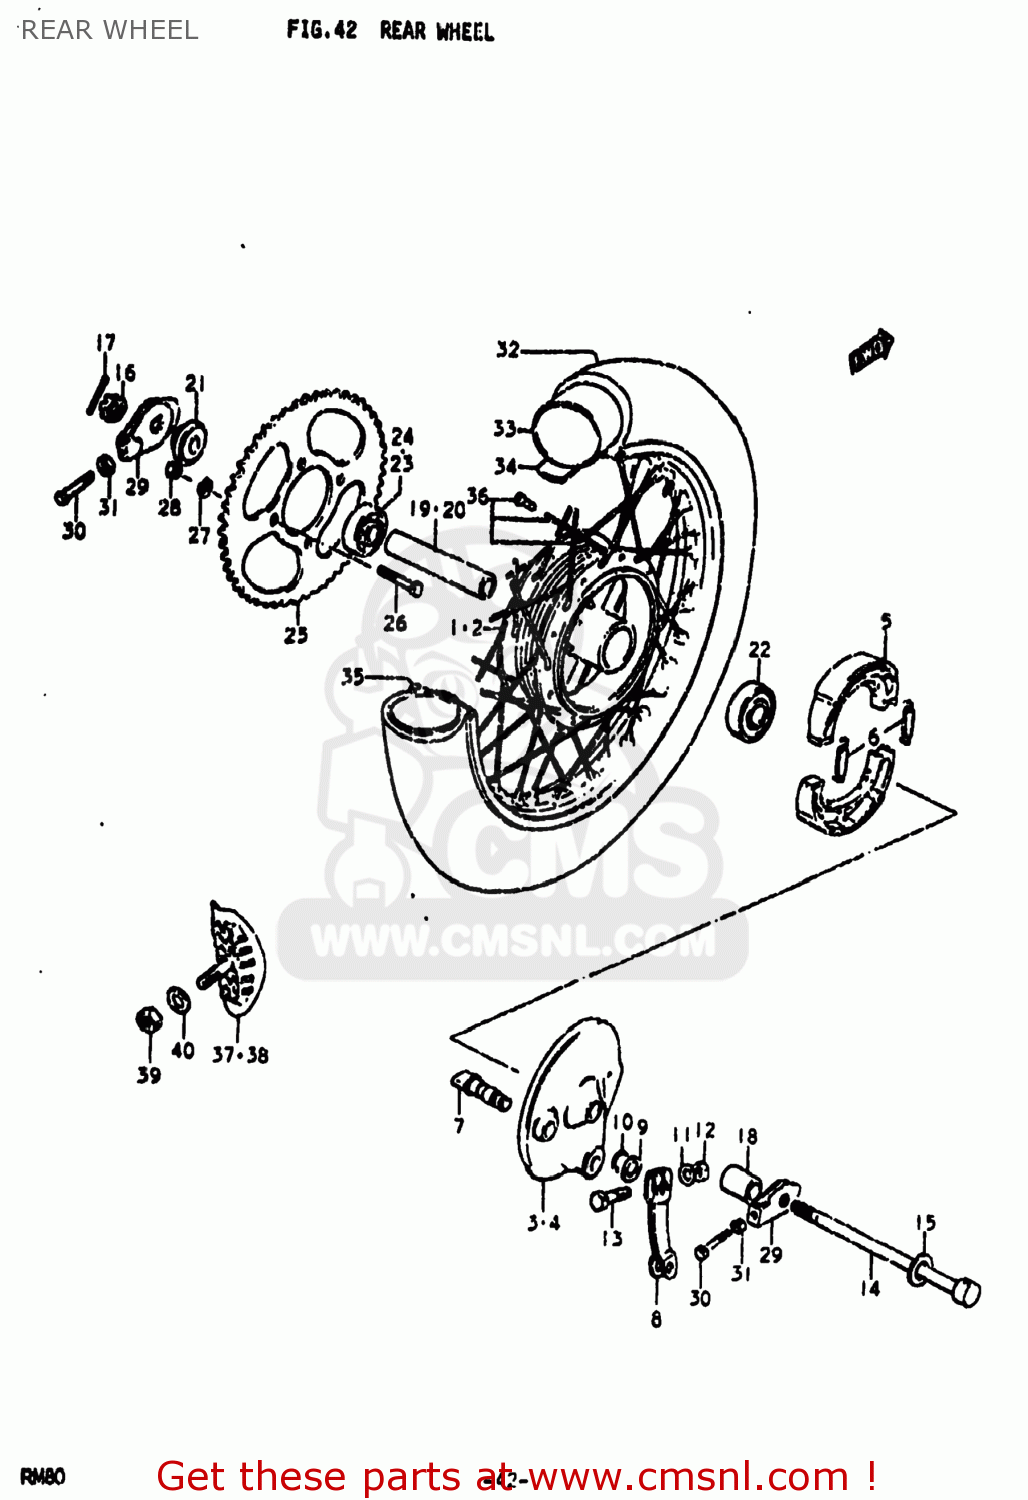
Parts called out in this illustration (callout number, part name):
1	DRUM,REAR HUB
2	DRUM,REAR HUB
3	PANEL,REAR BRAKE ANCHOR
4	PANEL,REAR BRAKE ANCHOR
5	SHOE,BRAKE
6	SPRING(L:34)
7	CAM,FRONT BRAKE
8	LEVER,REAR BRAKE CAM
9	WASHER (14.5X22X1.6)
10	O-RING (D:2.4 ID:13.8)
11	WASHER
12	NUT
13	BOLT(6X33)
14	AXLE,REAR
15	WASHER
16	NUT 12MM
17	COTTER PIN
18	SPACER (12.1X22X27)
19	SPACER(12.6X19X91)
20	SPACER (12.6X19X79)
21	SPACER,RR AXLE,L
22	BEARING, RH
23	BEARING
24	BEARING
25	SPROCKET,REAR
26	BOLT
27	LOCK WASHER
28	NUT
29	ADJUSTER,CHAIN,R
30	BOLT(6X38)
31	NUT
32	TIRE
33	TUBE,INNER
34	PROTECTOR,INNER TUBE
35	RIM,REAR WHEEL
36	SPOKE SET,REAR
37	STOPPER,BEAD
38	STOPPER,BEAD
39	NUT
40	WASHER
